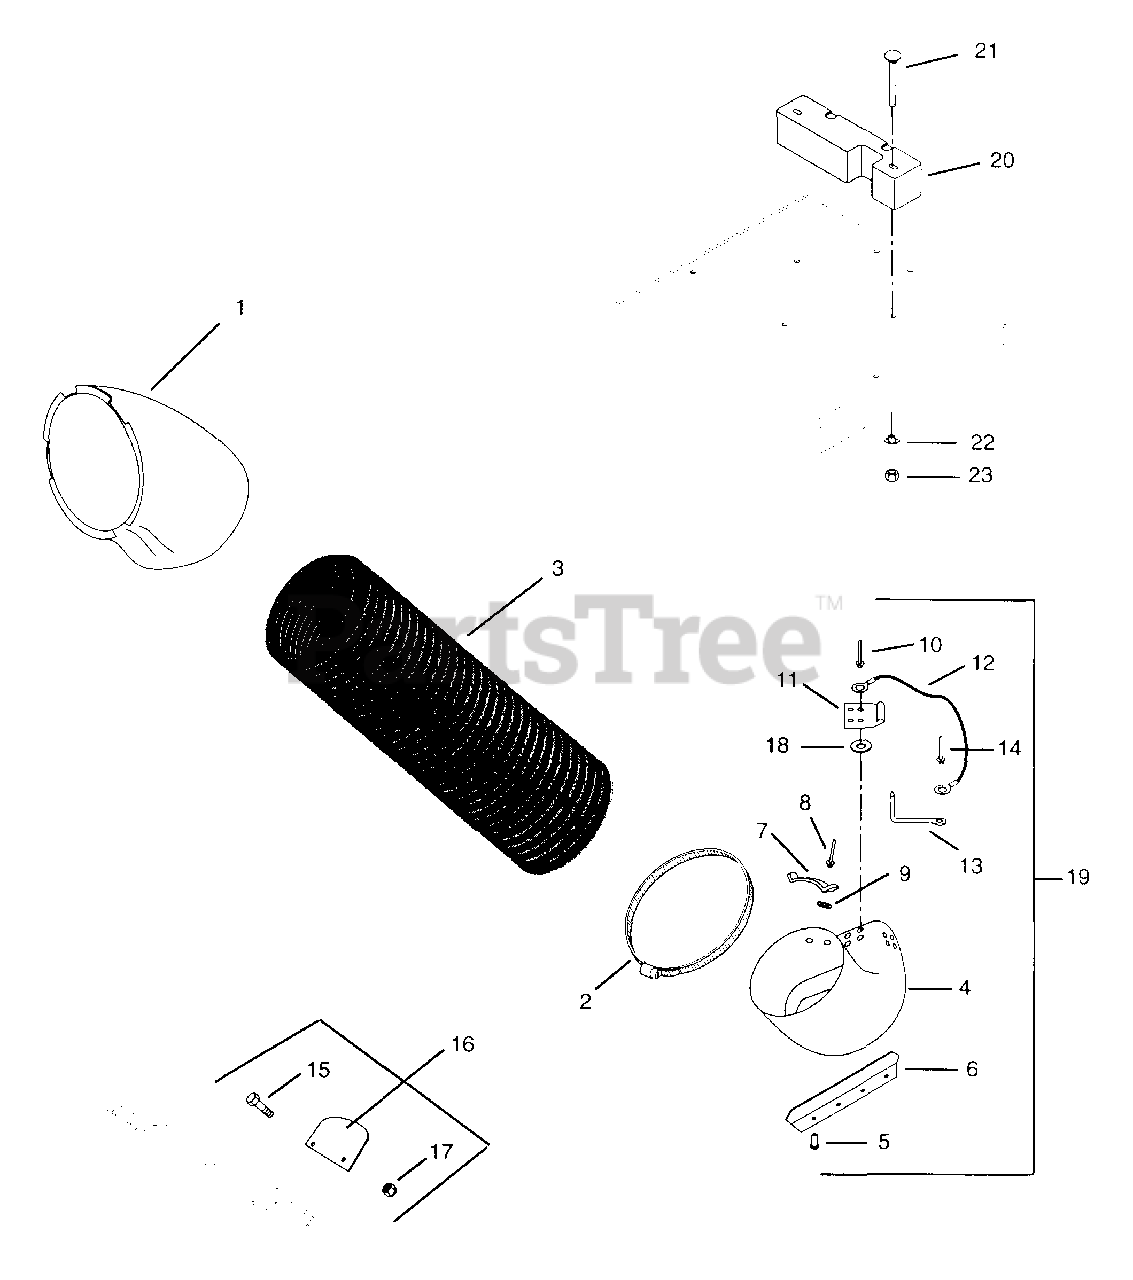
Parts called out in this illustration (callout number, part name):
1	BAGGER BOOT - UPPER
2	CLAMP-HOSE WRM 2.13/8.62X.56
3	HOSE 7X38
4	PAN BOOT ASSEMBLY
5	RVT-TBLR .187X.375 OH ST PL
6	EXTENSION-CHUTE
7	TUBE RETAINER CLIP
8	RVT-POP.187X.527 DOME ST
9	WSHR-FL-STL .215X.56X.085 PL
10	RVT-POP .187X.402 DOME ST
11	BOOT BRACKET
12	LANYARD
13	PULL PIN
14	RVT-TBLR .187X.375 ST-AL PL
15	BLT-HEX .38-16X2.00 GR8
16	SERVICE VANE PACKAGE
17	NUT-LK TOP .312-24 PL GR C
18	WSHR-FL-STL .194X.492X.047 PL
19	MOWER BOOT ASSY- 40"
20	COUNTER WEIGHT
21	BLT-RDHDSQNK .44-14X4.50 PL
22	WSHR-LK-INT .438 YWZC
23	@NUT-HEX .44-14 YWZC
